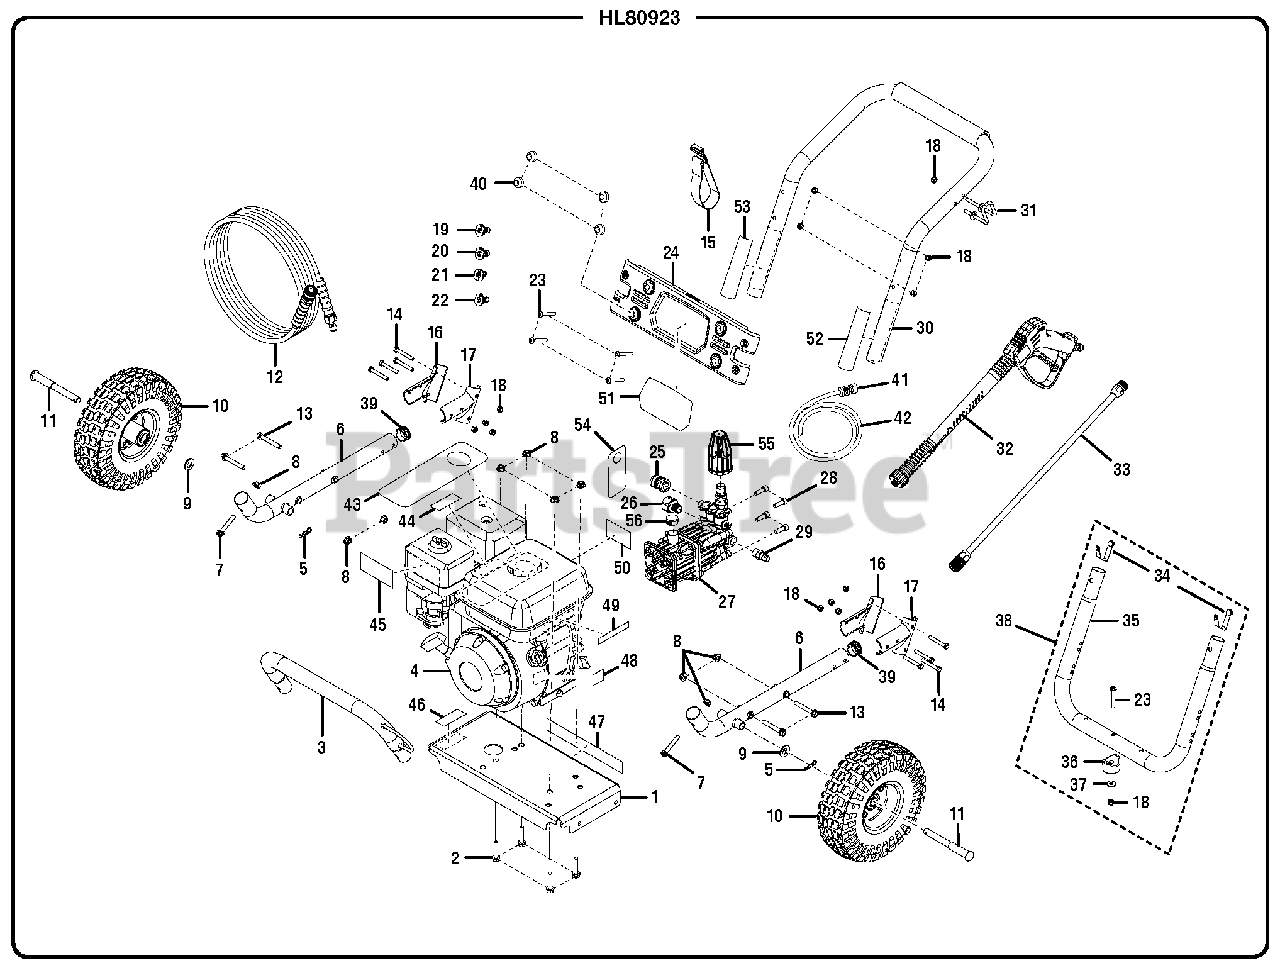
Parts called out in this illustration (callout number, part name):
1	Engine Plate
2	Bolt (M8 x 36 mm, Flange Hd.)
3	Front Frame
5	Hitch Pin
6	Main Frame Assembly
7	Bolt (M8 x 45 mm, Flange Hd.)
8	Lock Nut (M8 x 1-1/4 in.)
9	Washer (1/2 in.)
10	Wheel (10 in. x 13 in.)
12	High Pressure Hose (30 ft.)
13	Bolt w/Washer (M8 x 55 mm, Hex Hd.)
14	Bolt (1/4 x 52 mm, Hex Hd.)
15	Hose Storage Strap (Velcro)
16	Handle Bracket (Left)
17	Handle Bracket (Right)
18	Lock Nut (1/4-20)
19	0 Degree Nozzle
20	25 Degree Nozzle
21	Soap Nozzle
22	40 Degree Nozzle
23	Screw (1/4-20 x 2 in., T30, Torx Hd.)
24	Hose and Nozzle Holder Assembly
25	Quick Disconnect (3/8 in.)
27	Pump
28	Hex Bolt (5/16 x 23 mm)
29	Thermal Relief Valve
30	Handle w/Grip Assembly
31	Wand Holder
32	Trigger Handle Assembly
33	Wand
34	Spring Clip Assembly
35	Rear Frame
37	Washer (1/4 in.)
38	Rear Tube Assembly
39	Handle Tube Cap
40	Rubber Grommets
41	Chemical Siphon Filter
42	Chemical Siphon Tube
43	Hang Tag (Oil)
44	Hot Muffler Label
45	Performance Label (Air Box)
46	Warning Label
47	Data Label
48	UL Fire Warning Label
49	Low Oil Label
50	Honda Logo
51	Performance Label (Upper Accessory)
52	Engine Quick Start Label
53	Quick Start Pump Label
54	Vent Cap Hang Tag
55	Pressure Adjustment Knob
